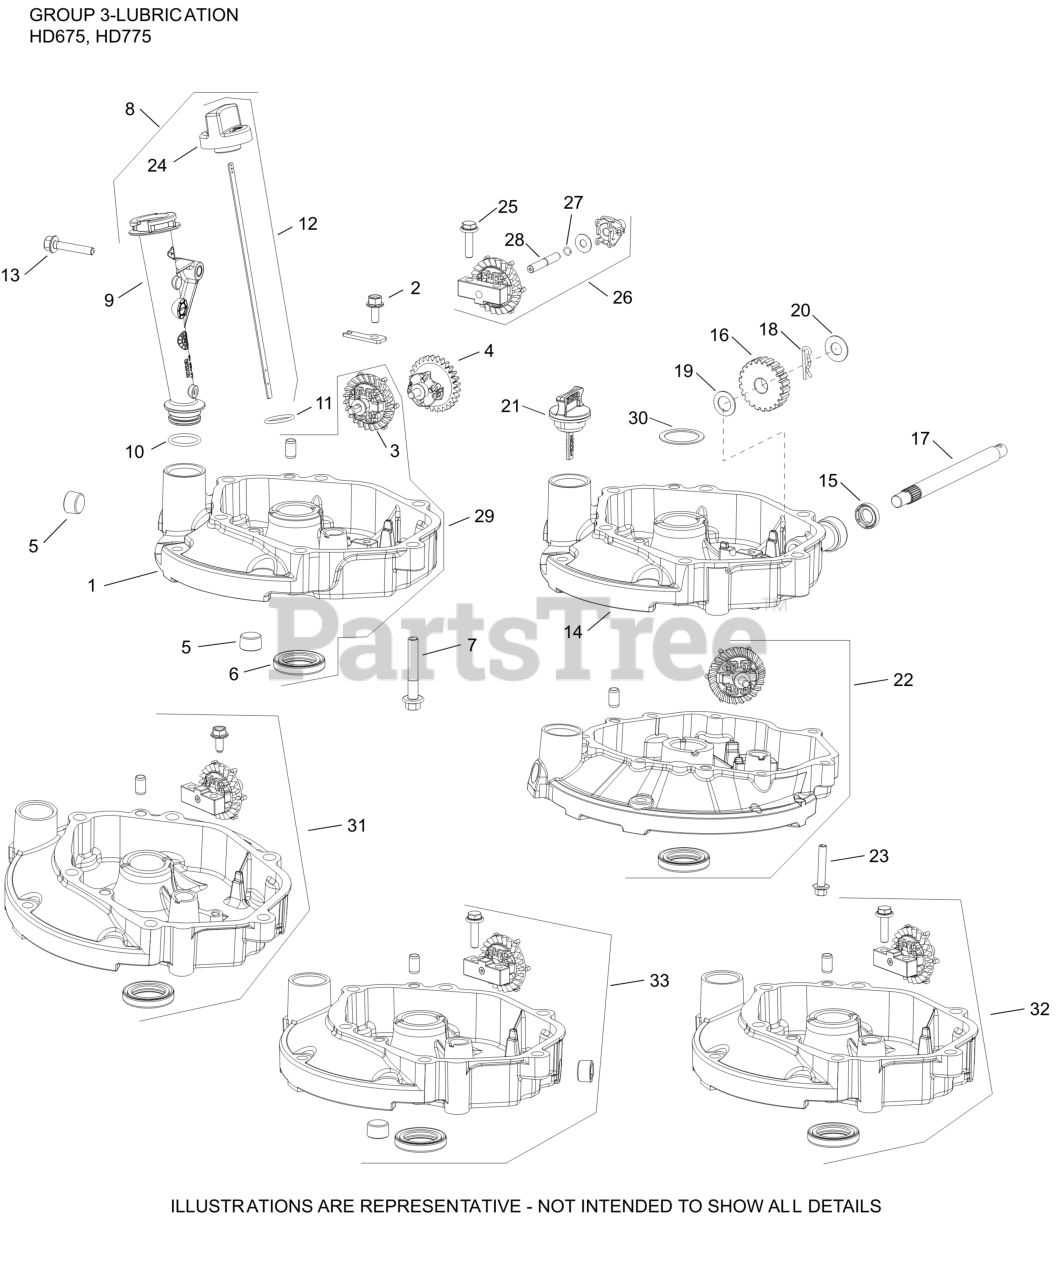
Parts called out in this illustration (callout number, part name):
1	KIT, OIL PAN
5	PLUG, PIPE (W/SEALANT)
7	SCREW, HEX FLANGE (M8)-USE 25 086 456-S
8	KIT, DIPSTICK AND TUBE
9	TUBE, OIL FILL
13	SCREW, HEX FLANGE (M6)-(#25086435S)
24	CAP, DIPSTICK-USE 14 227 23-S
NI	GEAR ASSEMBLY, GOVERNOR
